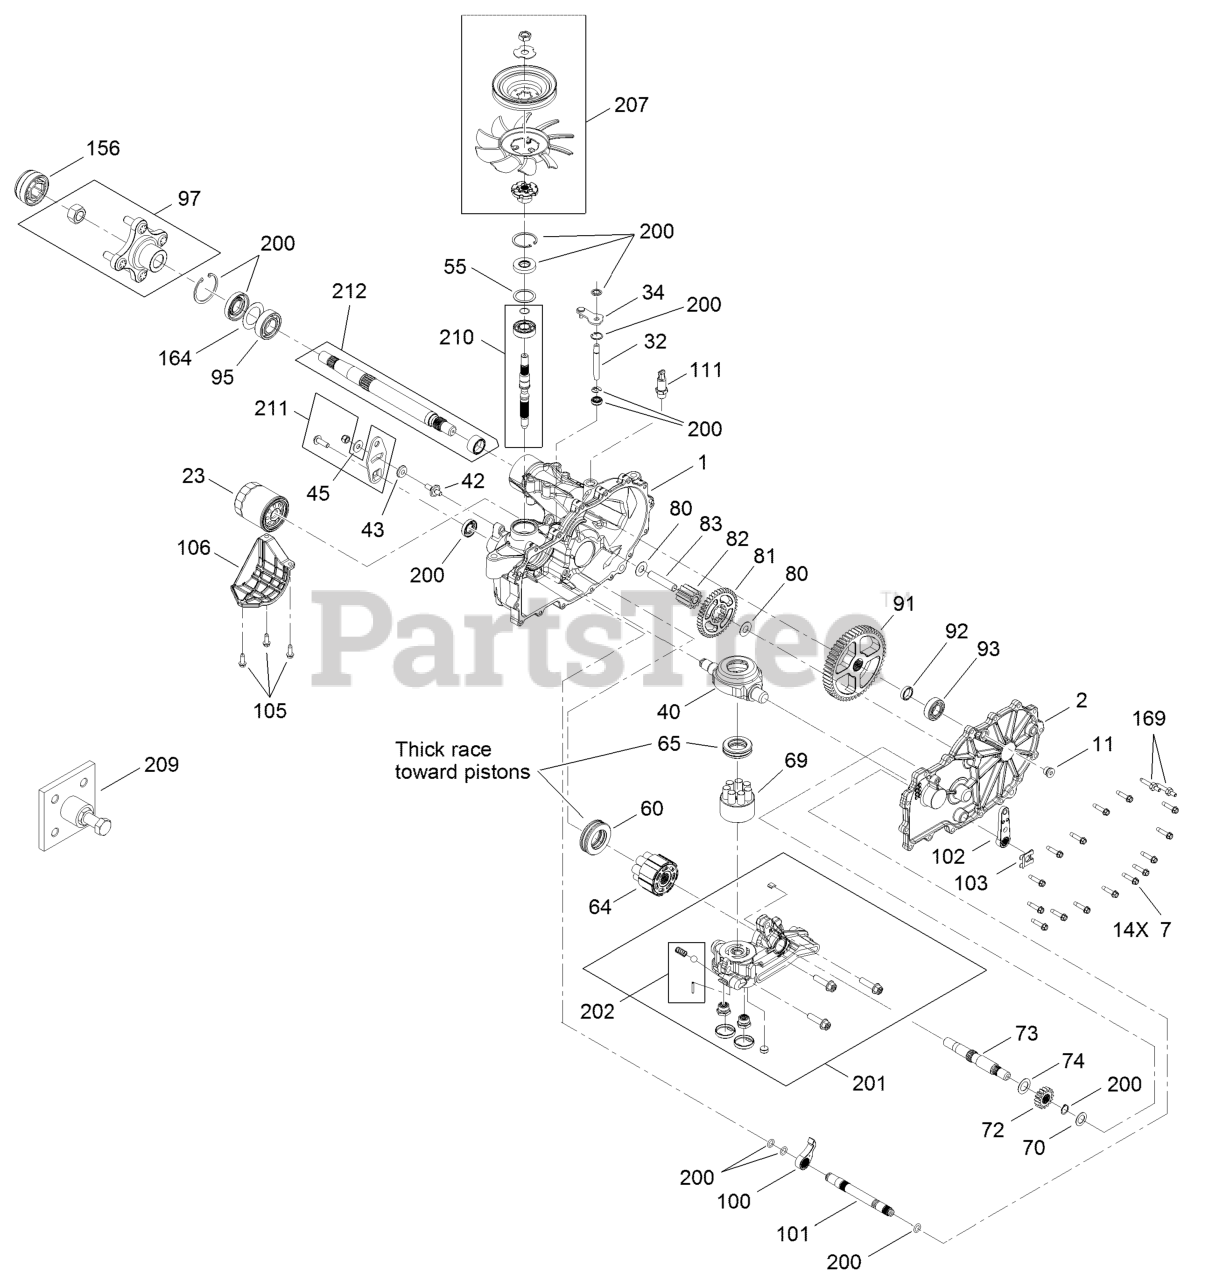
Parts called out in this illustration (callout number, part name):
1	MAIN HOUSING KIT
2	RH HOUSING SIDE KIT
7	SCREW-HHF
11	PLUG-THREAD, STRAIGHT
23	ELEMENT-OIL FILTER, HYD
32	ROD-BYPASS
40	SWASHPLATE-TRUNNION
43	PUCK-FRICTION
60	BEARING-THRUST
64	MOTOR CYLINDER BLOCK KIT
65	BEARING-THRUST
69	PUMP BLOCK ASM
70	WASHER-FLAT
72	GEAR-16T
73	SHAFT-MOTOR
81	GEAR-43T
82	GEAR-11T
83	PIN-JACKSHAFT
91	GEAR-54T
93	BEARING-BALL
95	BEARING-BALL
97	HUB KIT
100	PAWL-BRAKE
101	SHAFT-BRAKE, INBOARD
102	HANDLE-BRAKE
103	CLIP-RETAINING
106	GUARD-FILTER, RH
111	ADAPTER-STRAIGHT
156	COVER-NUT, AXLE
200	SEAL KIT
201	RH CENTER SECTION KIT
202	CHARGE RELIEF KIT
207	FAN PULLEY KIT
210	INPUT SHAFT KIT
211	CONTROL ARM KIT
212	AXLE SHAFT KIT
